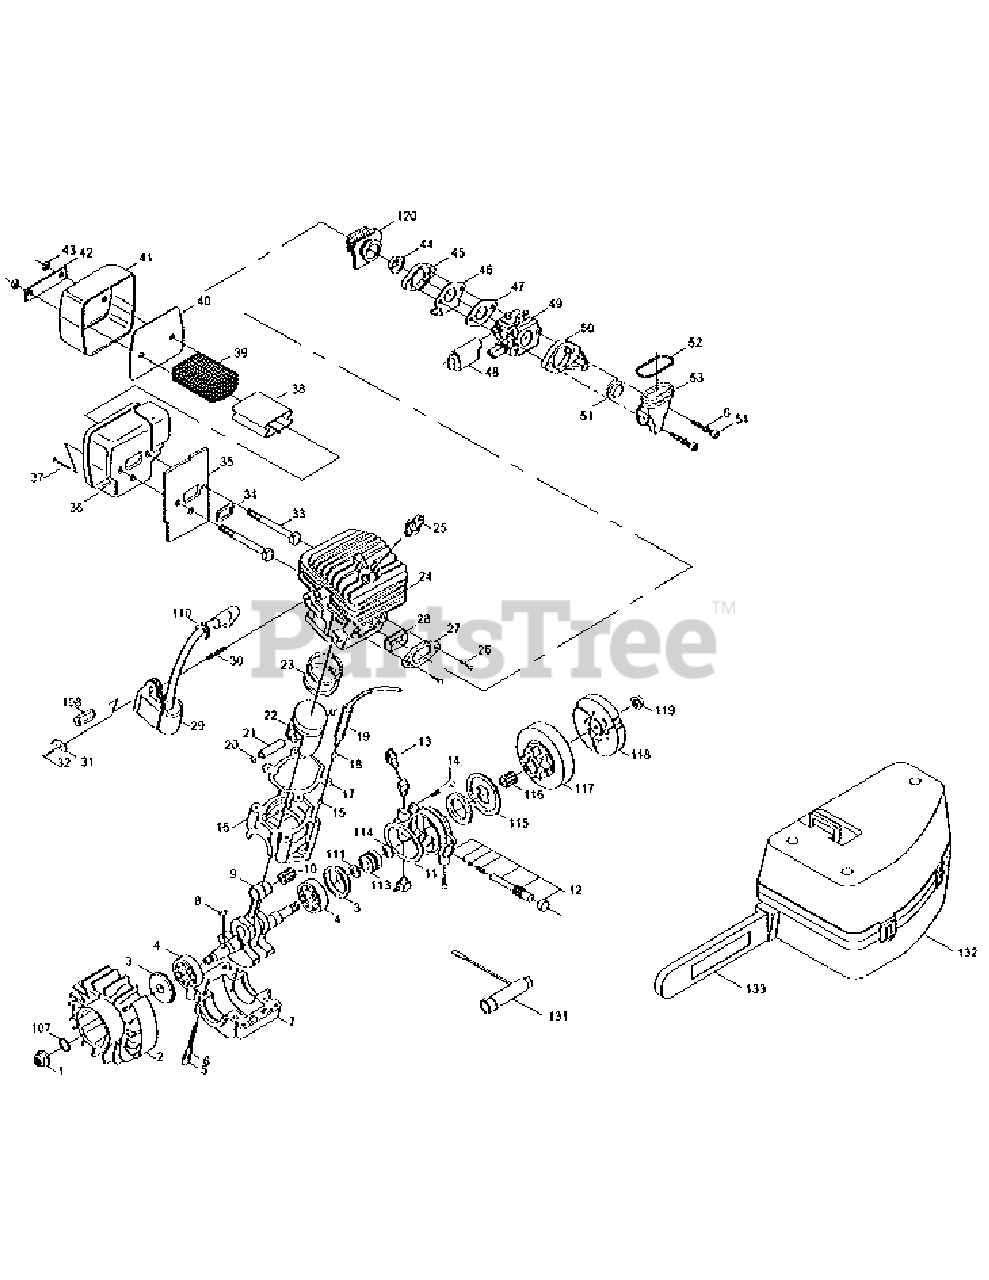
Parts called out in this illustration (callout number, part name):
7	CRANKCASE LOWER
9	C'SHAFT/C'ROD ASS'Y
12	PUMP ASS'Y
13	CONNECTOR
15	FITTING, PULSE LINE
16	CRANKCASE UPPER
18	CLAMP, WIRE HOSE
19	CONDUIT, FLEX
23	RING, PISTON
25	SPARK PLUG
26	SCREW
29	IGNITION ASS'Y
31	CONTACT, CROUNT
36	MUFFLER BODY ASS'Y
37	SCREW
41	COVER, MUFFLER
42	LOCKPLATE
55	STARTER ASS'Y
58	METAL CLIP
60	FUEL/OIL TANK ASS'Y
61	PRIMER, PREMOTE
66	CAP, FUEL
67	FILTER, FUEL
70	BOOT, CARB
71	VALVE DUCKBILL
76	PLATE, BAR
77	PLATE, FLANGE
80	HANDLE ASS'Y
81	COVER ASS'Y
83	SCREW
84	AIR CLEANER ASS'Y
87	CHOKE ASS'Y
88	ROD, CHOKE
90	ISOLATOR ASS'Y
91	CABLE ASS'Y
92	COVER ASS'Y HANDLE
96	ISOLATOR ASS'Y
102	RELEASE TRIGGER
103	LATCH, HIGH IDLE
105	FRAME, REAR
113	GEAR, WORM
117	DRUM SPRKT ASS'Y
118	CLUTCH ASS'Y
120	BOOT, CARB
122	SCREW
123	18 INCH CHAIN
123	20 INCH CHAIN
124	18 INCH BAR
124	20 INCH BAR
126	CHAIN BRAKE ASS'Y
132	CARRY CASE
